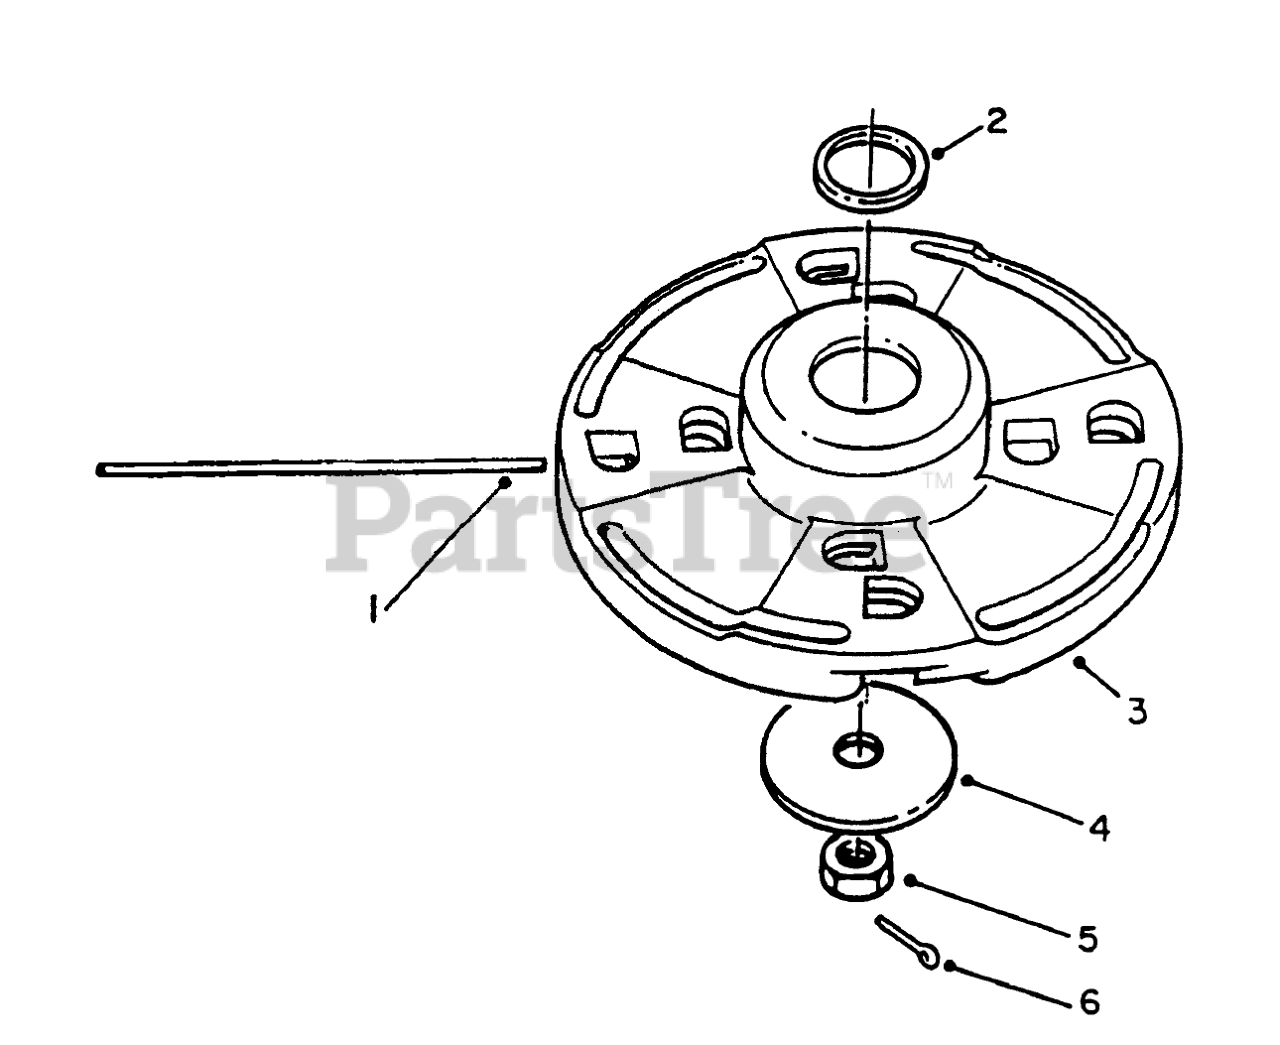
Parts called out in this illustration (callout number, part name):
1	Line-Cutting
2	SPACER
3	Head Assembly (Incl.Ref.#2)
4	WASHER
6	1/16 X 1 LG COTTER PIN
